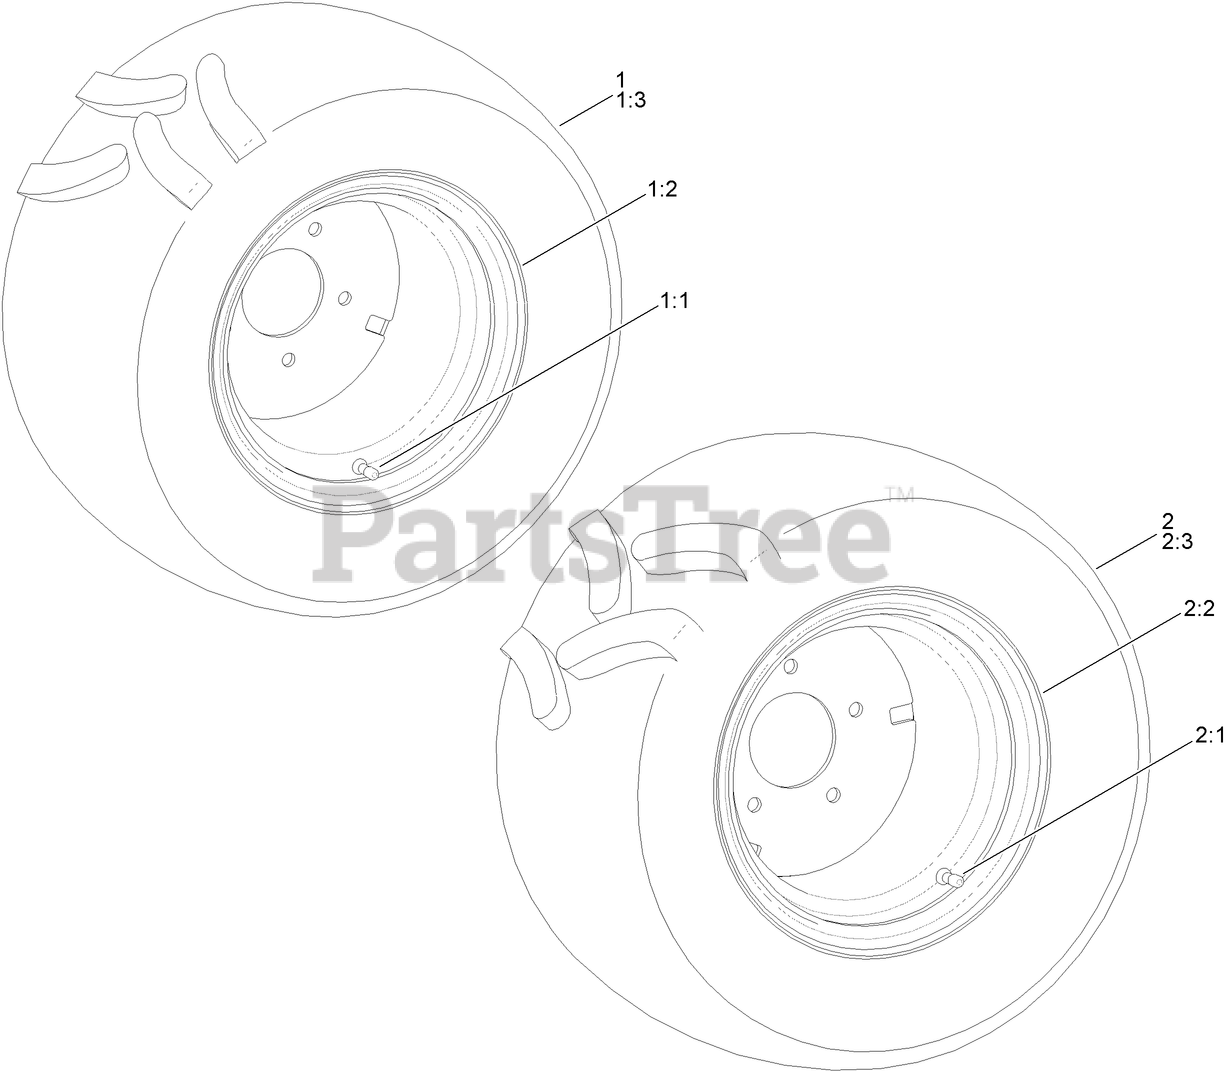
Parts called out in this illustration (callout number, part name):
1	RH WHEEL AND TIRE ASM
1:1	STEM-VALVE
2	LH WHEEL AND TIRE ASM
2:1	STEM-VALVE
